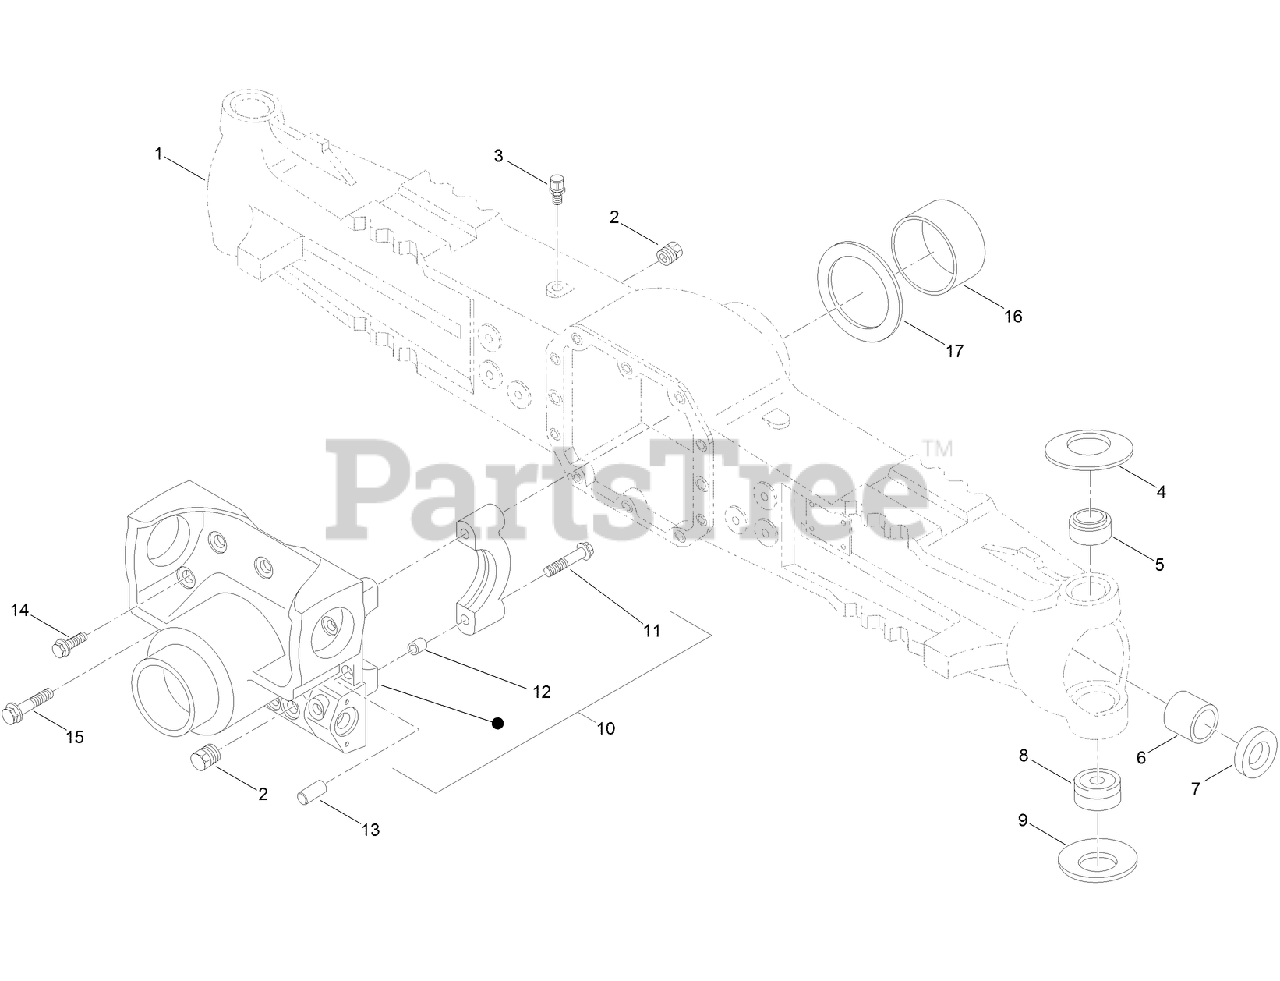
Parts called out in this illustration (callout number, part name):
1	HUB and BEARING ASM
3	BREATHER
4	WASHER-BELLEVILLE
5	BUSHING
6	BUSHING
7	SEAL-RING
8	BEARING-SPHERICAL
9	WASHER-BELLEVILLE
10	SUPPORT-DIFFERENTIAL
12	BUSHING-CENTERING
16	BUSHING
17	WASHER
